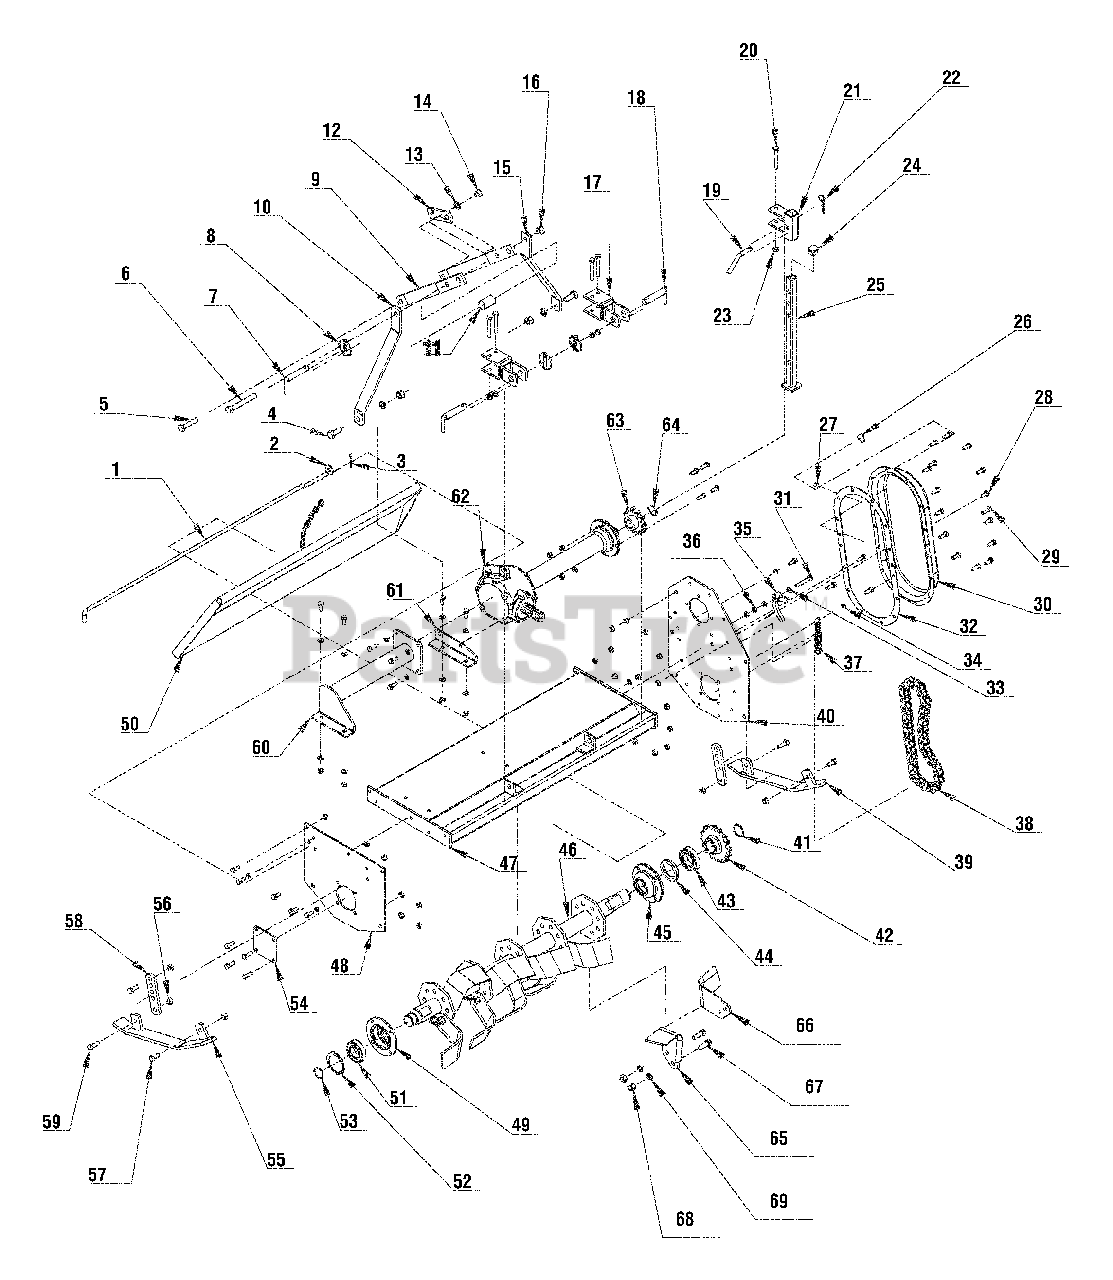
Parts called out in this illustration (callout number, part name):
1	Rod, Shield Pivot
7	Pin, Center Link
9	Arm, Top Hitch
10	Support, Top Hitch
11	Spacer, 33.7 x 3.6
12	Bracket, Chain
17	Bracket, Lower Link
18	Pin, Lower Link
20	Bolt, M10 x 80 8.8
21	Bracket, Stand
28	Bolt, M10 x 25 8.8
29	Bolt, M10 x 30
30	Cover, Chain Case
31	Bolt, M10 x 65 8.8
32	Gasket, Cover
35	Tensioner, Chain
39	Shoe, RH Skid
40	Panel, RH Side
42	Sprocket, Tine Shaft
43	Bearing, Tine Shaft
44	Spacer, 49.5 x 80 x 10
45	Retainer, Bearing
47	Frame, Tiller
48	Panel, LH Side
49	Retainer, Bearing
50	Shield, Tine Trail
51	Bearing, Tine Shaft
55	Shoe, LH Skid
57	Bolt, M12 x 30 8.8
58	Plate, Height Adjustment
59	Bolt, M12 x 35 8.8
60	Tube, Support
61	Bracket, Gearbox Mounting
62	Gearbox Complete
63	Sprocket, Gearbox
65	Tine, Tiller LH
66	Tine, Tiller RH
67	Bolt, M14 x 1.5 x 40 8.8
68	Nut, M14 x 1.5
